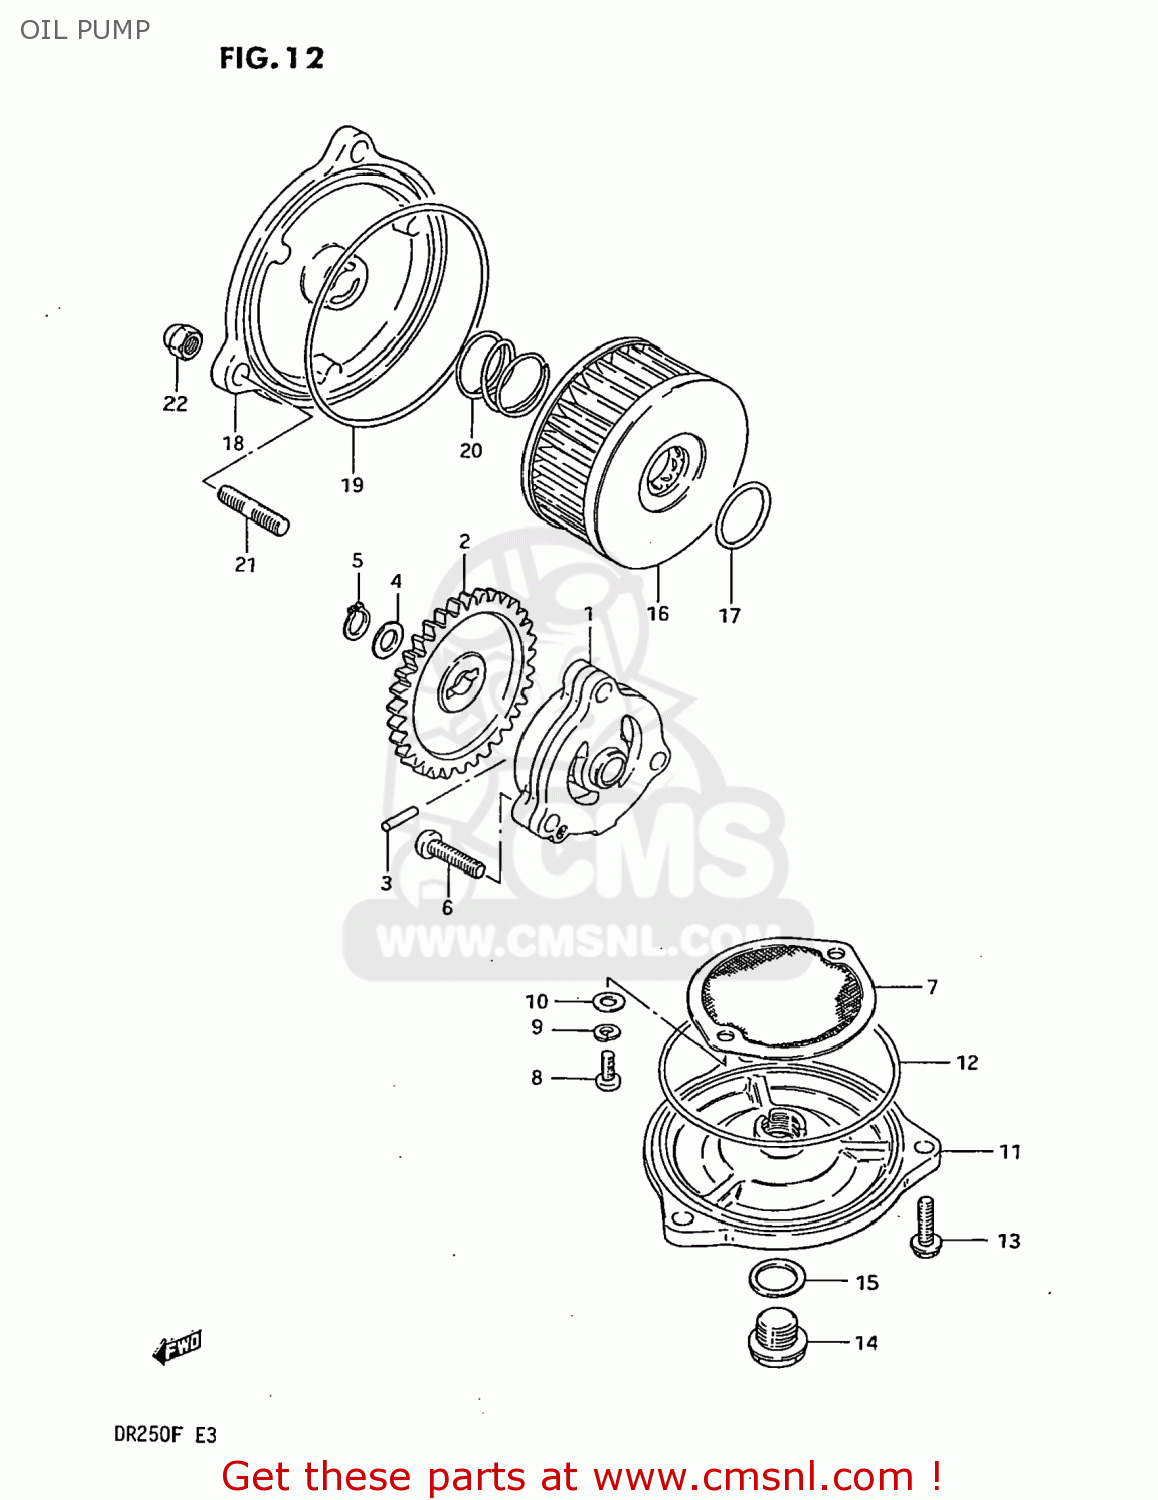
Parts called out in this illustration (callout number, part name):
1	PUMP ASSY,ENGINE OIL
2	GEAR,OIL PUMP DRIVEN(NT:33)
3	PIN(4X15.8)
4	SHIM
5	CIRCLIP
6	SCREW
7	STRAINER,ENGINE OIL
8	SCREW 5X12
9	LOCK WASHER
10	WASHER
11	CAP,OIL STRAINER
12	O RING(D:2.4,ID:85)
13	BOLT (6X20)
14	PLUG
15	GASKET(14X19.2X2) (NAS)
16	FILTER ASSY,ENGINE OIL
17	O RING(D:2.4,ID:15.8)
18	CAP,OIL FILTER
19	O RING(D:2.4,ID:73)
20	SPRING
21	STUD 6X12
22	NUT 6MM
